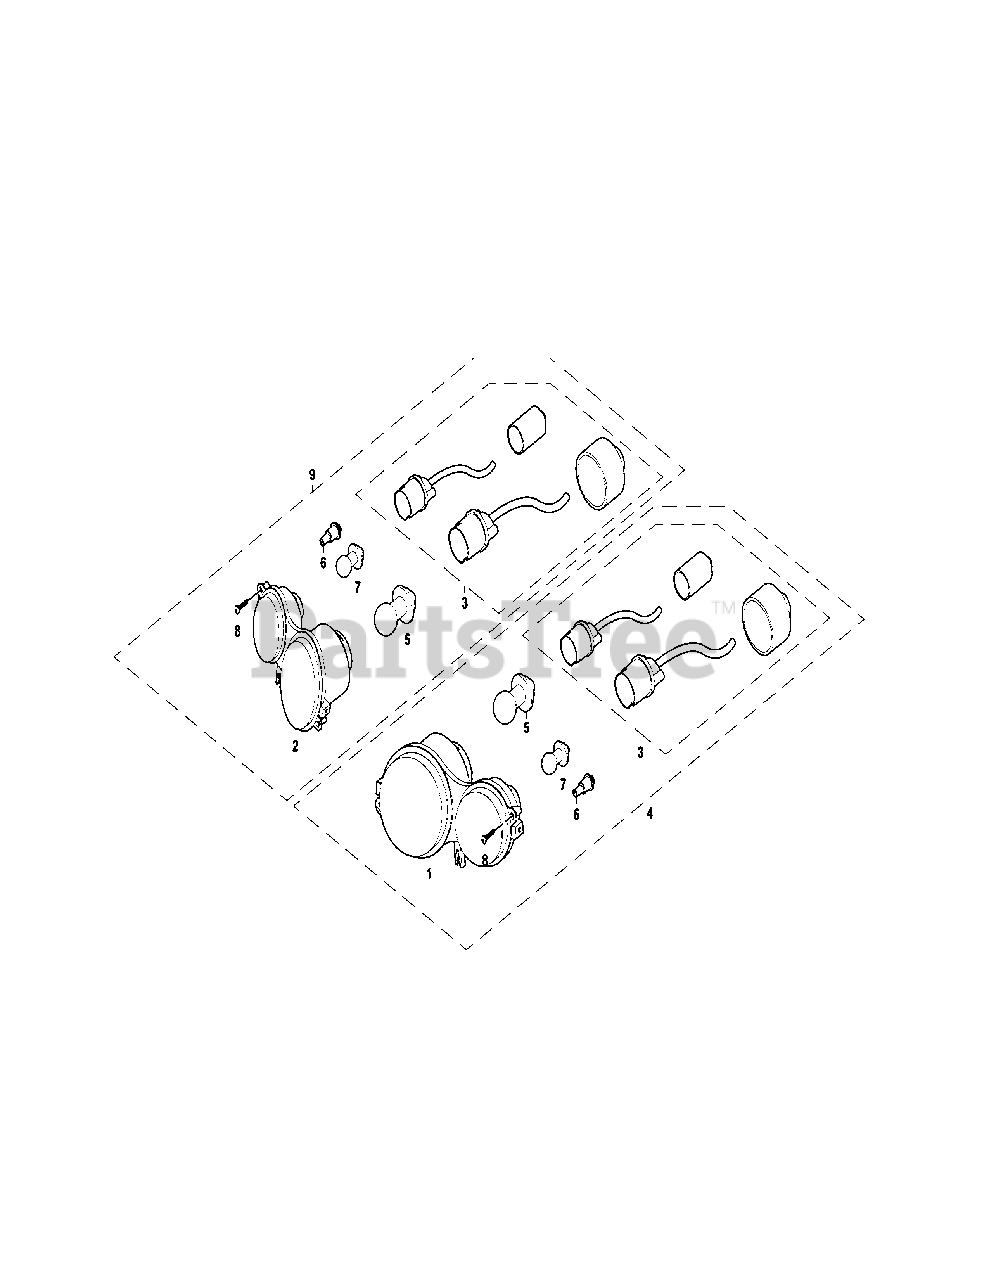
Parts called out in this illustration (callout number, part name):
1	Lamp Housing (L)
2	Lamp Housing (R)
3	Headlight Cable
4	Left Headlight Assy (Model A)
5	Front Headlight Bulb (12V 35W/35W)
6	Position Light Bulb (12V 5W)
7	Front Turninglight Bulb (12V 10W)
8	Cross Recessed Plate Head Tapping Screws ST3.5×9.5
9	Right Headlight Assy (Model A)
